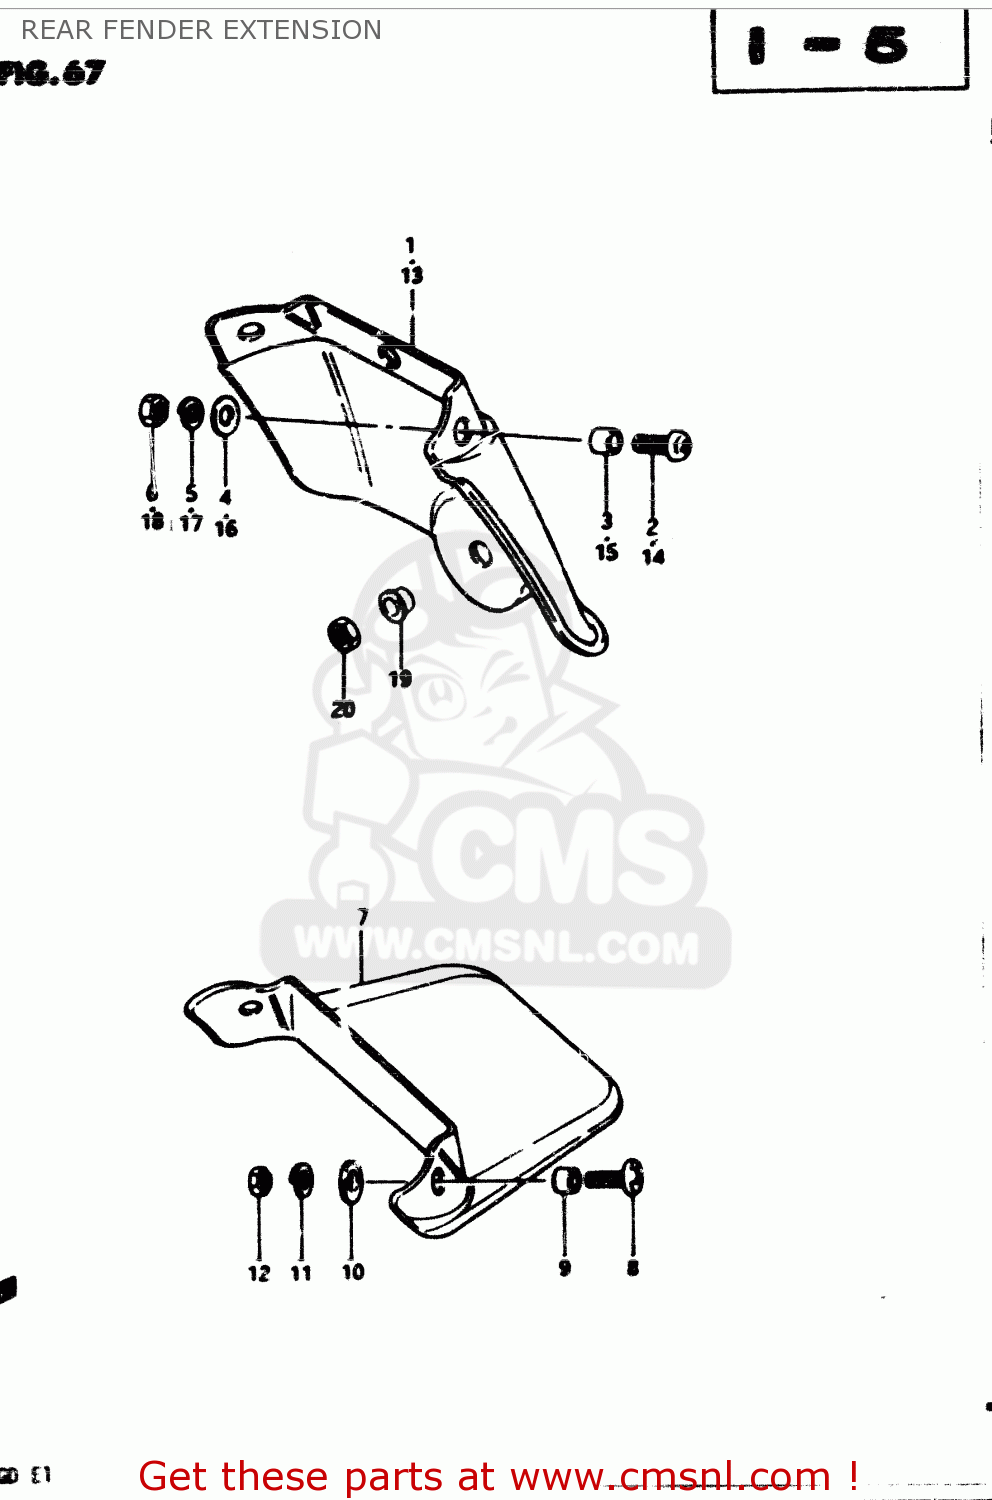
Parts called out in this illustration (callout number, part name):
1	EXTENSION,REAR FENDER
2	SCREW (6X15)
3	SPACER(6.2X8.3X5.7)
4	WASHER(6.5X18X1)
5	LOCK WASHER
6	NUT
7	EXTENSION,REAR FENDER
8	SCREW (6X15)
9	SPACER(6.2X8.3X5.7)
10	WASHER(6.5X18X1)
11	LOCK WASHER
12	NUT
13	EXTENSION,REAR FENDER
14	SCREW (6X15)
15	SPACER(6.2X8.3X5.7)
16	WASHER(6.5X18X1)
17	LOCK WASHER
18	NUT
19	SPACER
20	NUT
